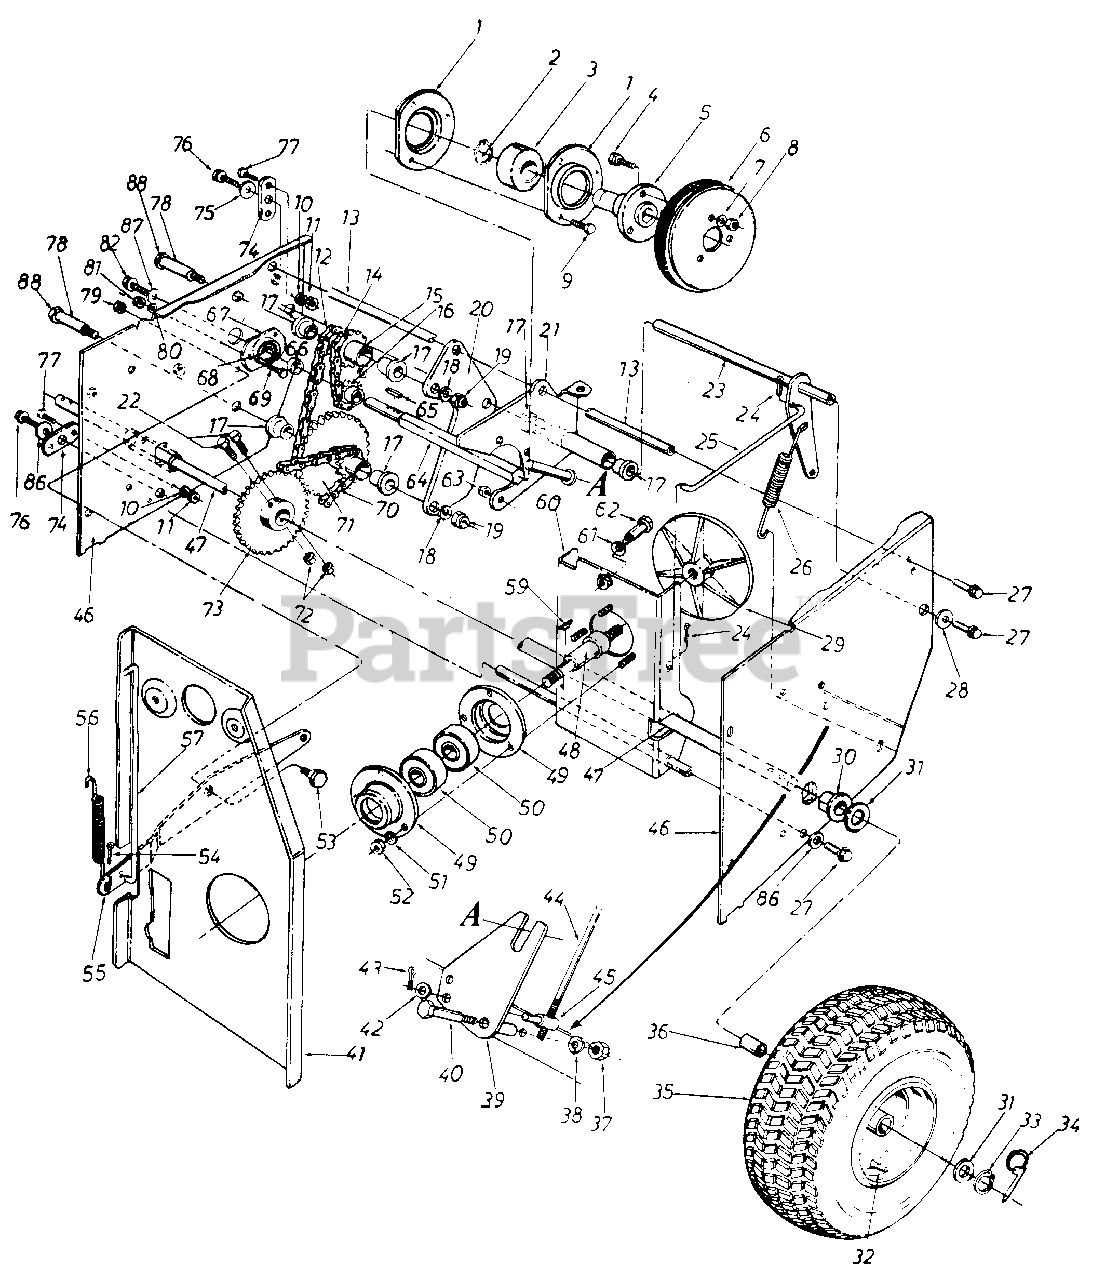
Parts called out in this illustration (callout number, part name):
1	Bearing Housing
2	Snap Ring-1.0" Dia.
3	Ball Brg. .25MM x 52MM x 15MM Thk.
4	Hex Sems Bolt 5/16-18 x .75" Lg.
5	Friction Wheel Adapter
6	Friction Wheel Ass'y.
7	L-Wash. 5/16" I.D.
8	Hex Nut 5/16-18 Thd.
9	Hex Bolt 1/4-28 x .62" Lg.
10	L-Wash. 1/4" I.D.
11	Hex Nut 1/4-20 Thd.
12	#41 Chain-1/2" Pitch x 43 Links
13	Sliding Support Axle
14	#41 Chain-1/2" Pitch x 19 Links
15	9 and 14 Teeth Sprocket Hub Ass'y.
16	8 Teeth Sprocket
17	Flange Bearing .63" I.D.
18	L-Wash. 3/8" I.D.-H.D.
19	Hex L-Jam Nut 3/8-24 Thd.
22	Hex Bolt 5/16-24 x 1.75" Lg.
23	Drive Clutch Brkt. Ass'y.
24	Inter. Cot. Pin 5/16" Dia.
25	Drive Clutch Rod .31" Dia. x 7.38" Lg.
26	Extension Spring 4.31" Lg.
27	Hex L-Bolt 5/16-18 x .62"
28	Fl-Wash. .345" I.D. x .75" O.D.
29	Aluminum Drive Plate
30	Flange Brg. w/Flats
31	Thrust Washer 1.03" I.D.
32	Tubeless Air Valve
33	Snap Ring 1.0" Shaft
34	Klick Pin
35	Wheel Ass'y. Comp. 16 x 4.8
36	Bearing 1.0" I.D.
37	Hex Jam Nut 3/8-16 Thd.
38	L-Wash. 3/8" I.D.
41	Engine Brkt. Ass'y.
42	Fl-Wash. .344" I.D. x .62" O.D.
43	Cotter Pin 3/32" Dia. x .75" Lg.
44	Shifting Rod
45	Adjustment Ferrule
46	Frame Ass'y.
47	Free Wheeling Axle
48	Drive Plate Spindle
49	Bearing Housing
50	Ball Brg. .787" I.D. x 1 85" O.D.
51	L-Wash. 5/16" I.D.
52	Hex Nut 5/16-18 Thd.
53	Shld. Bolt .625" Dia. x .170" Lg.
54	Inter. Cotter Pin 5/16" Dia.
55	Auger Clutch Brkt.
56	Extension Spring .38" O.D. x 3.18" Lg.
57	Auger Clutch Rod .31" Dia. x 10.62" Lg.
59	#61 Hi-Pro Key 3/16" x 5/8" Dia.
62	Shld. Bolt
63	Hex Ins. Jam Nut 1/4-28 Thd.
64	Hex Shaft
65	#9 Hi-Pro Key 3/32" x 5/8" Dia.
66	Spacer .51" I.D. x .69" O.D.
67	Bearing Housing
68	Ball Bearing
69	Hex Bolt 1/4-20 x .62" Lg.
70	#420 Chain .50" Pitch x 37 Links
71	9 and 32 Teeth Sprocket Hub Ass'y.
72	Hex L-Nut 5/16-24 Thd.
73	28 Teeth Sprocket Hub Ass'y.
74	Pivot Axle Brkt.
75	Fl-Wash. .345" I.D. x .75"
76	Hex L-Bolt 5/16-18 x .62"
77	Hex Bolt 1/4-20 x .62" Lg.
78	Sprocket Hub Tubing 1.88"
79	Hex Cent. L-Nut 3/8-16 Thd.
80	L-Wash. 1/4" I.D.
81	Hex Nut 1/4-20 Thd.
82	Hex L-Bolt 5/16-18 x .62"
86	Fl-Wash. .344" I.D. x .875"
87	Bell-Wash. .345" I.D. x .88"
88	Hex Bolt 3/8-24 x 2.75" Lg.
